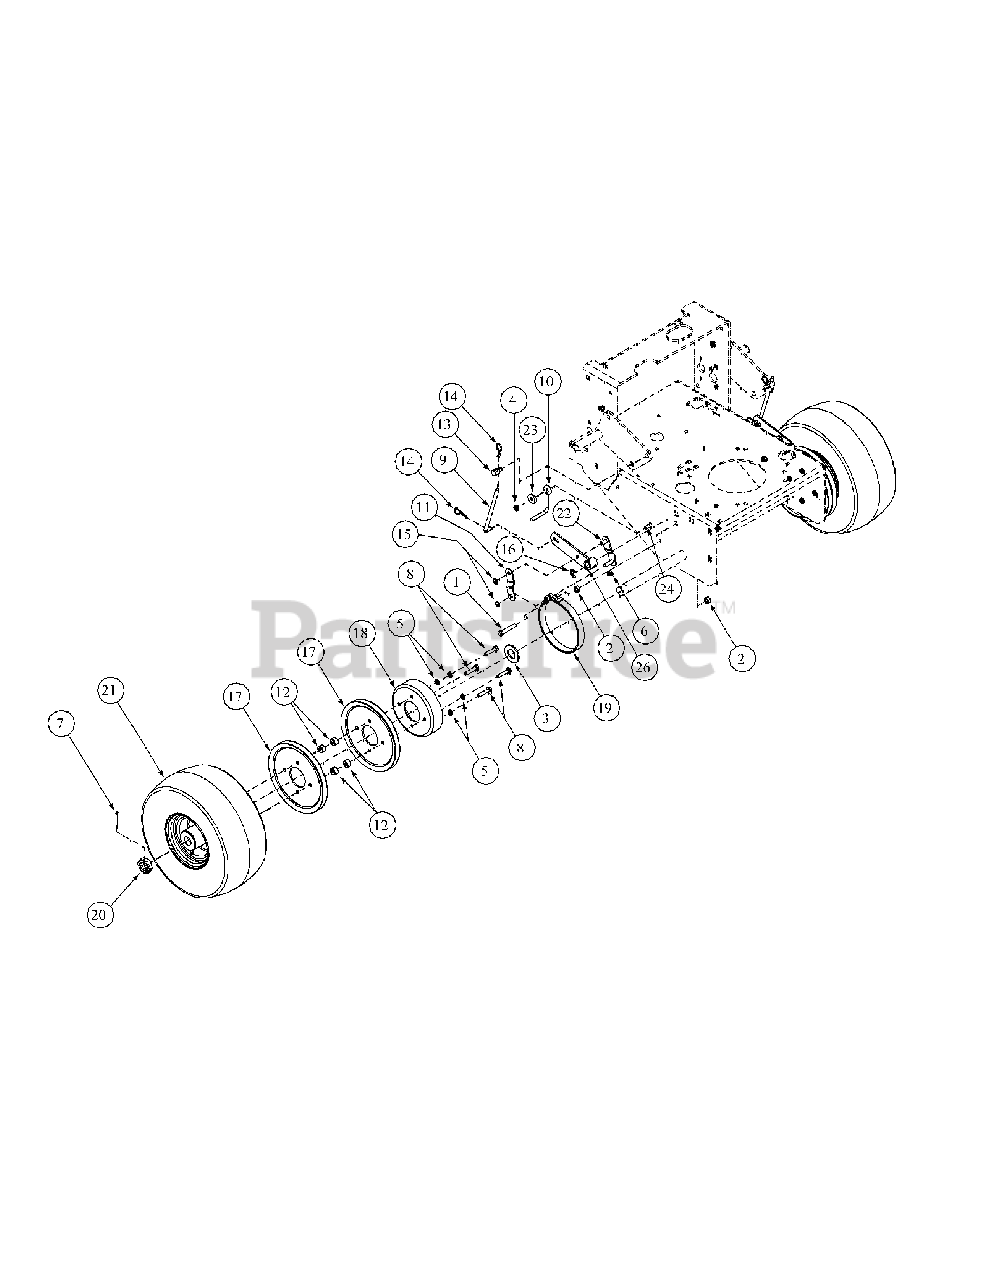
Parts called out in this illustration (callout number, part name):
1	Hex Cap Screw, 3/8-16, 2.00
2	Hex Nut, 3/8-16
3	Flat Washer, 2.000 x 1.005 x .120
4	Nut, Nylock, 5/16-18
5	Lock Washer, 5/16 Zinc
6	Grease Fitting, 1/4-28, 90°
7	Cotter Pin, 5/32 x 1-1/2 Zinc
8	Hex Cap Screw, 5/16-18 x 1-1/2
9	Brake Rod
10	Drive Belt Guide
11	Brake, Bracket Link
12	Drive Wheel Pulley Spacer
13	Swivel Joint
14	Hair Pin, 3/8-1/2
15	Retainer, Push ON, 3/8
16	E-Ring, 5/8
17	Drive Pulley, V
18	Drum Brake
19	Band Brake
20	Hex Jam Nut, 1-14
21	Wheel Assembly, 13 x 5.00-6
22	Brake Link
23	Idler Washer
24	Carriage Bolt, 5/16-18 x 1
26	Brake Lever Weldment
